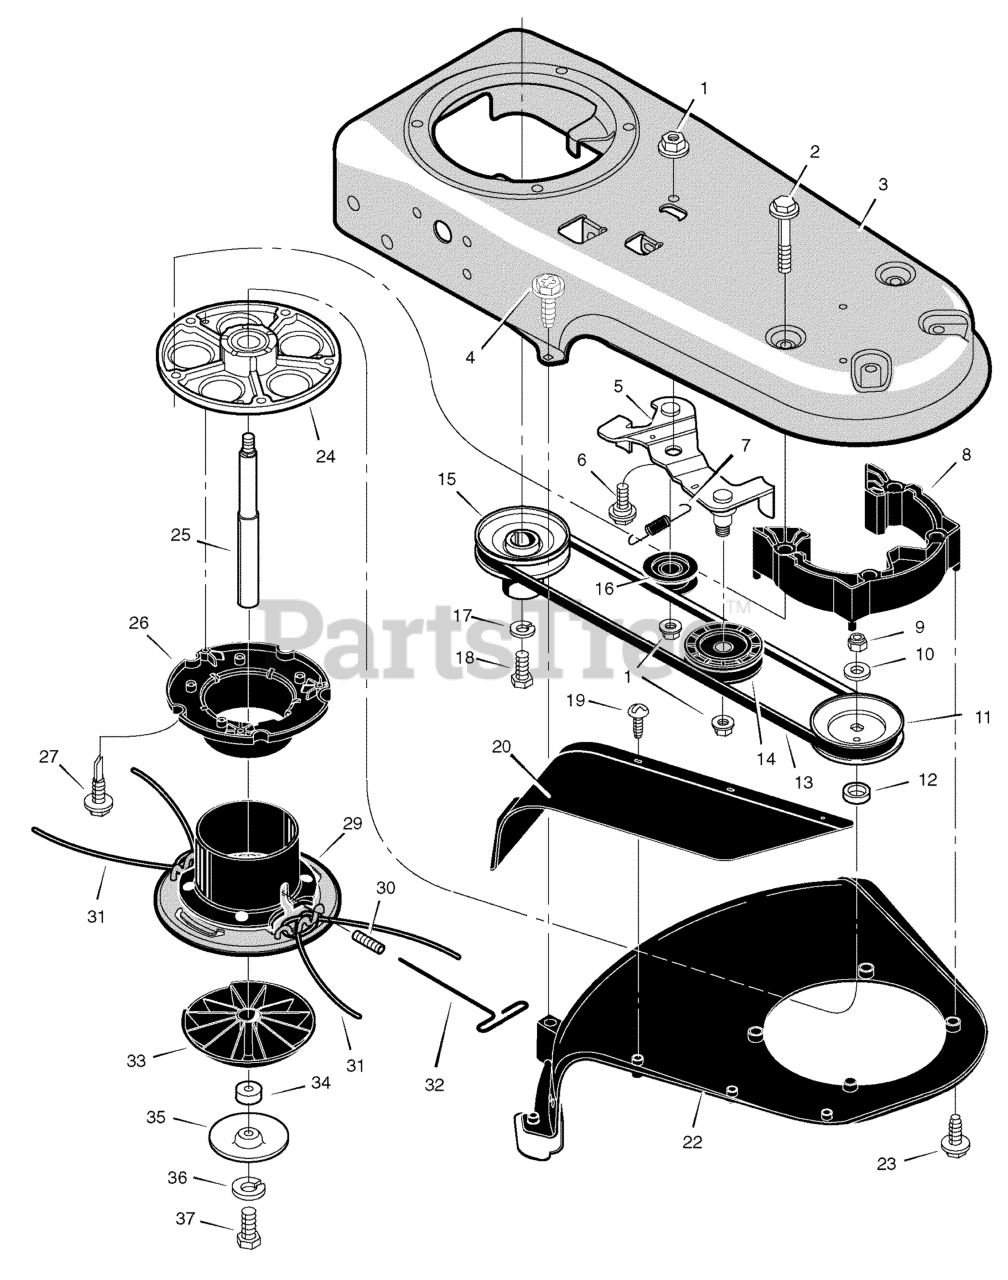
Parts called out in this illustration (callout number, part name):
1	Nut
3	Frame, Trimmer
5	Bracket, Idler Assembly
7	Spring, Extension
8	Spacer Assembly, Jackshaft
10	Washer, Flat
11	Pulley, Cutting Head
12	Spacer, Upper Pulley
13	Belt, Trimmer
14	"V" Pulley
15	Pulley, Engine
16	Pulley, Idler
17	Lockwasher
20	Flap, Depris
22	Shield, Trimmer
24	Housing, Jackshaft
25	Shaft, Cutting Head
26	Wrap, Weed
29	Assembly, Cutter Head & Wrap
31	Line, Trimmer 0.155 X 21.25
32	Wrench, T-Handle
33	Guide, Height
34	Spacer, Shield
35	Spacer, Abrasion
36	Washer
